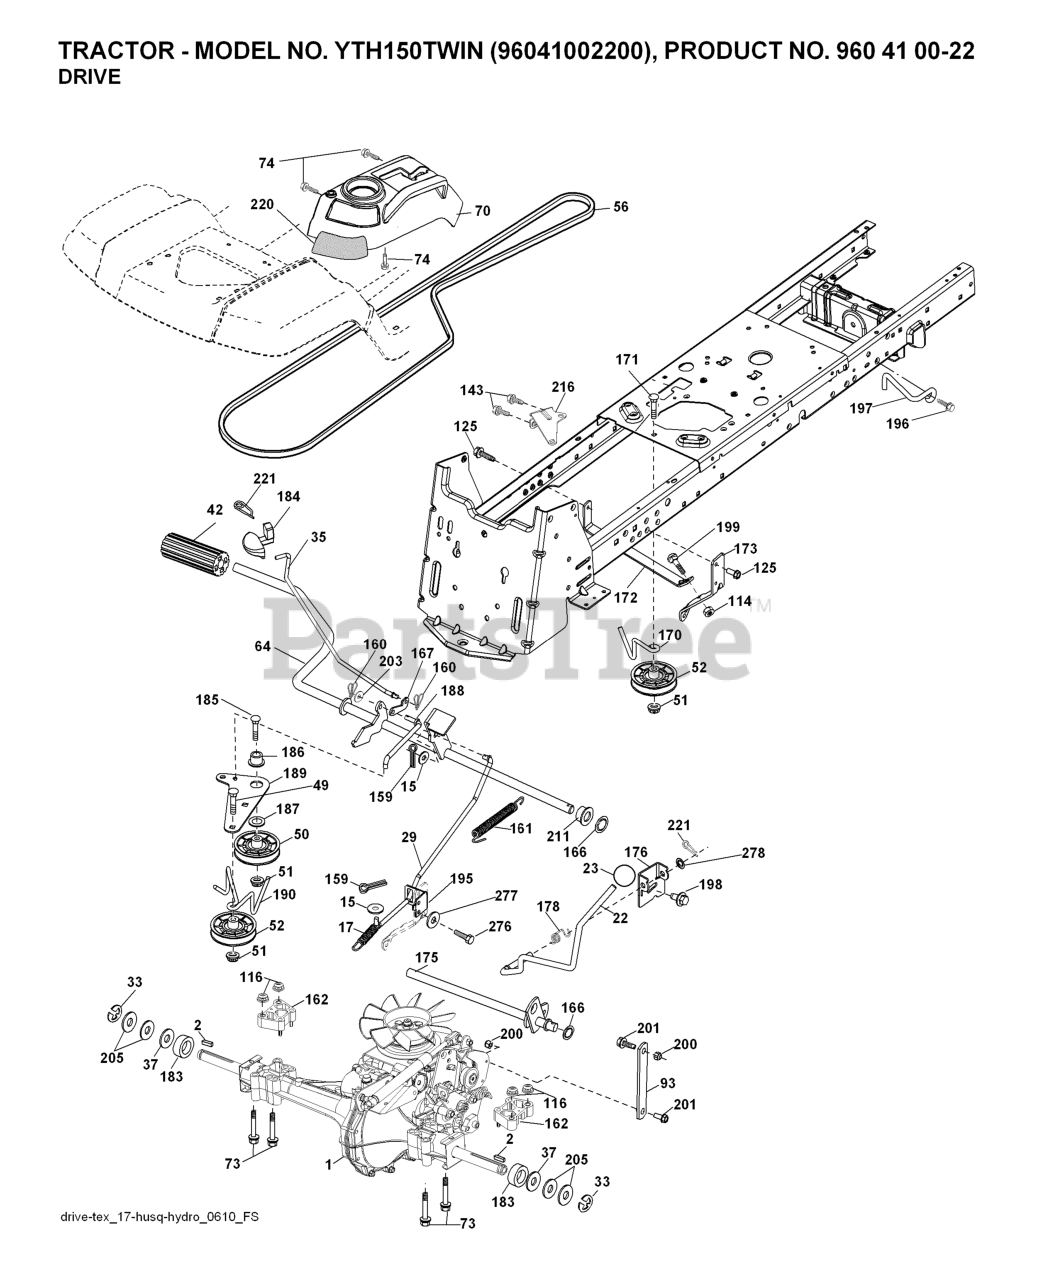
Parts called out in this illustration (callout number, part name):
2	SQUARE KEY
15	WASHER
17	SPRING.BRAKE.HG3000/3500
22	SHIFTER.ASM.GT.TEX.2006
23	KNOB.DUCKHEAD.1/2
26	SPRING.RETURN.CRUISE
29	ROD.BRAKE.0610.PEDAL.CONTROL
35	ROD.BRAKE.PARKING.GT.H
42	PEDAL COVER T
50	IDLER.FLAT.910.OFFSET
51	NUT LOCK FLG 3/8-16 UNC
52	IDLER.V-GROOVE.1.688.OFFSET
64	SHAFT.ASM.PEDAL.BRAKE.
70	RP CONSOLE.ASM.HYDO.HUSQ.
73	BOLT.HEX.FLNG.5/16-18X3.75
74	SCREW.HI-LO.CONSOLE
93	LINK.SHIFT.T/A.0610.TE
114	NUT.71038.31-18.HEX.NYLOCK
116	NUT LOCK HEX FLANGE 5/16-18
125	SCREW
143	Screw 5/16-18 x 1/2 Hex, Self Tapping 5/16-18 x 1/2
159	COTTER PIN
160	RETAINER CLIP
161	SPRING.RETURN.CLUTCH.2006
162	SPACER.TRANSAXLE.18&22
166	NUT.PUSH.625.2006
167	LATCH.BRAKE.SPRING
170	KEEPER.V-IDLER.CENTER.
172	STRAP.TRQ.LH.FS.HG0510
173	STRAP.TORQUE.FS.0610.RH
175	SHAFT.ASM.SHFT.HG0510/
176	ARM.CLEVIS.ROD.SHIFT
178	SPRING.SHIFT.GT2006
183	SPACER AXLE
184	HANDLE.PARKG.BRK.HUSQ X667
186	SPACER.RETAINER
187	WASHER 12/32X2X10GA
188	RP.LINK.CLUTCH.GROUND.DRIVE
189	BELLCRANK.GROUND.DRIVE.TEX.
190	KEEPER.BELLCRANK.DRIVE
195	BRKT.ROD.BRAKE.18/20/2
196	SCREW 3/8-16X1
197	LINK.CLUTCH.ANIT-ROTAT
198	SCREW.7/16-14X7/8.FLAN
200	NUT.CENTERLOCK.5/16-
201	BOLT SHOULDER 5/16-18 UNC
203	WASHER
206	BRKT.MOUNT.LATCH.CRUIS
211	BUSHING.SHAFT.BRAKE.HAND
216	BRACKET.PULLEY.IDLER.W/TEX
220	REFLECTOR.RH.TEX GT
221	RETAINER.SPRING.CLIP.H
276	BOLT FIN HEX 7/16-14 X 1
277	WASHER SERRATED
278	NUT.PUSH.500.2006
